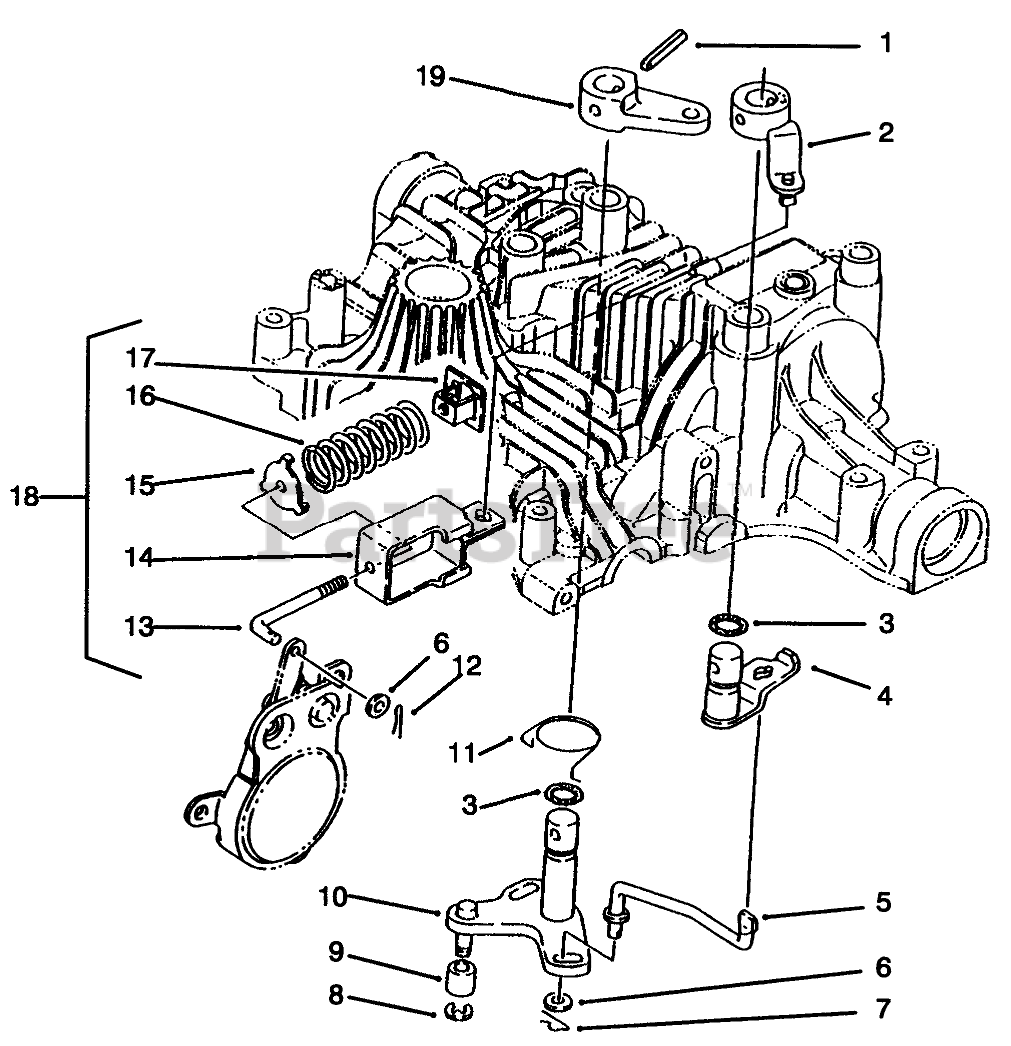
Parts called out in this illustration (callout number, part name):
1	PIN-ROLL
2	ARM-BRAKE B
3	O-RING
4	ARM-BRAKE A
5	ROD-BRAKE
6	WASHER
7	PIN - SNAP
9	BUSHING
10	SHAFT-BRAKE
11	RETURN-BRAKE
12	PIN-COTTER
13	ROD - ADJUSTER
14	HOLDER - SPRING
15	GUIDE - SPRING
16	SPRING
17	ADJUSTER
18	ROD ASM
19	ARM-BRAKE
